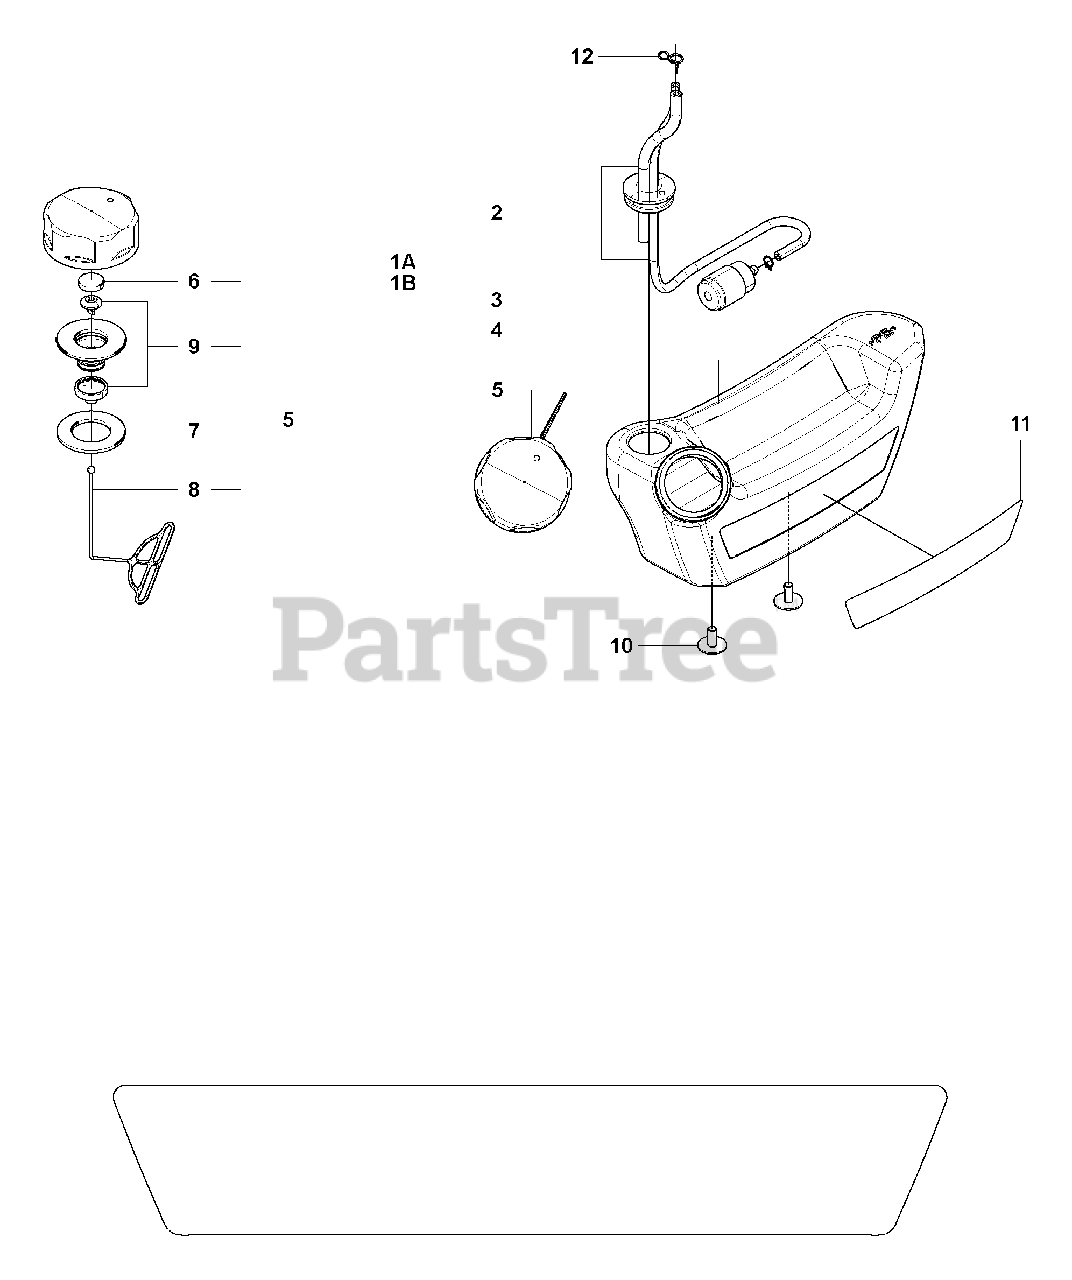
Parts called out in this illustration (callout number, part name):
1A	TANK-A
1B	TANK ASSY
2	PIPE C
3	FILTER
4	CLIP
5	ASSY FUEL CAP
6	FILTER
7	PACKING
9	HOLDER-A
11	LABEL TANK
12	CLIP
